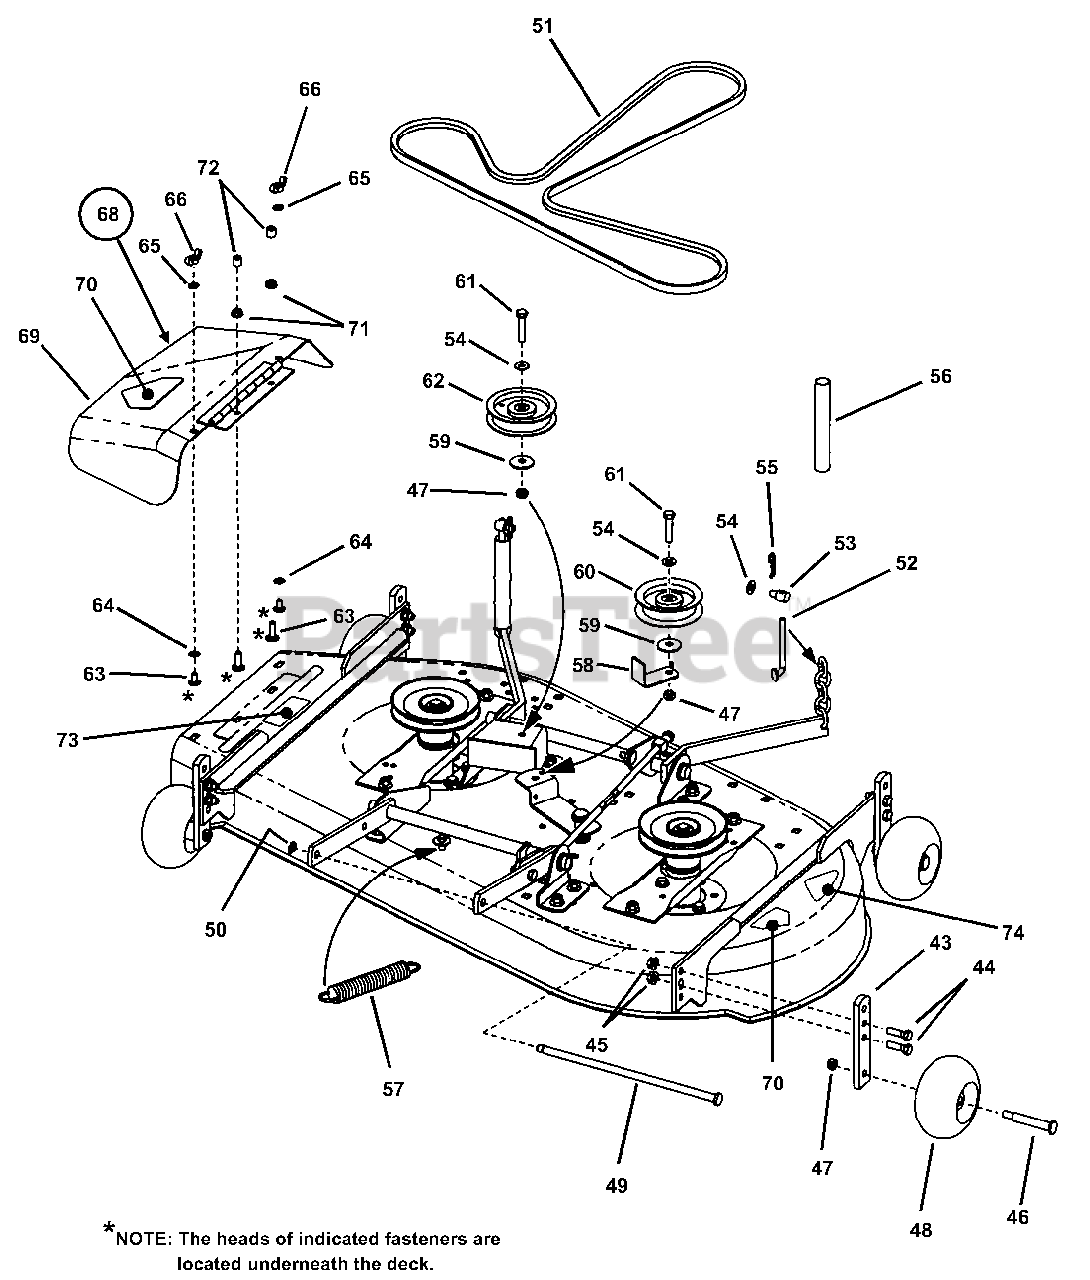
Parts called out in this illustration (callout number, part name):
43	POST, Anti-Scalp
44	SCREW, 3/8-16 x 1-1/4" Hex Head Cap, Grade 5
45	NUT, 3/8-16 Hex Flange
46	BOLT, 3/8-16 x 2-58" Shoulder
47	NUT, 3/8-16 Hex Center Lock
48	GAUGE WHEEL
49	ROD, Deck Support
50	RING, 7/16" External Retaining
51	BELT, HA, 94.5" Effective Length
52	ADJUSTER, Chain
53	SWIVEL, Adjustable
54	WASHER, 3/8" Flat
55	HAIR PIN, 3/32 x 1-1/2"
56	COVER, Chain
57	SPRING, External
58	GUIDE, 38"/42" Idler Belt
59	WASHER, Cone
60	IDLER, 4" Outside Diameter, Flat
61	SCREW, 3/8-16 x 1-3/4" Hex Head Cap
62	IDLER, 4.12" Outside Diameter, Flat
63	BOLT, 5/16-18 x 5/8" Short Neck Carriage, Grade 5
64	RETAINER, 5/16" Bolt
65	WASHER, 5/16" Split Lock
66	NUT, 5/16-18 Wing Lock
68	ASSEMBLY, Chute & Decal
69	CHUTE, Side (weldment)
70	DECAL, CPSC Heavy Adhesive
71	NUT, 5/16-18 Hex Flange Lock
72	CAP, Vinyl
73	DECAL, Chute/Deflector
74	DECAL, 42 Inch
